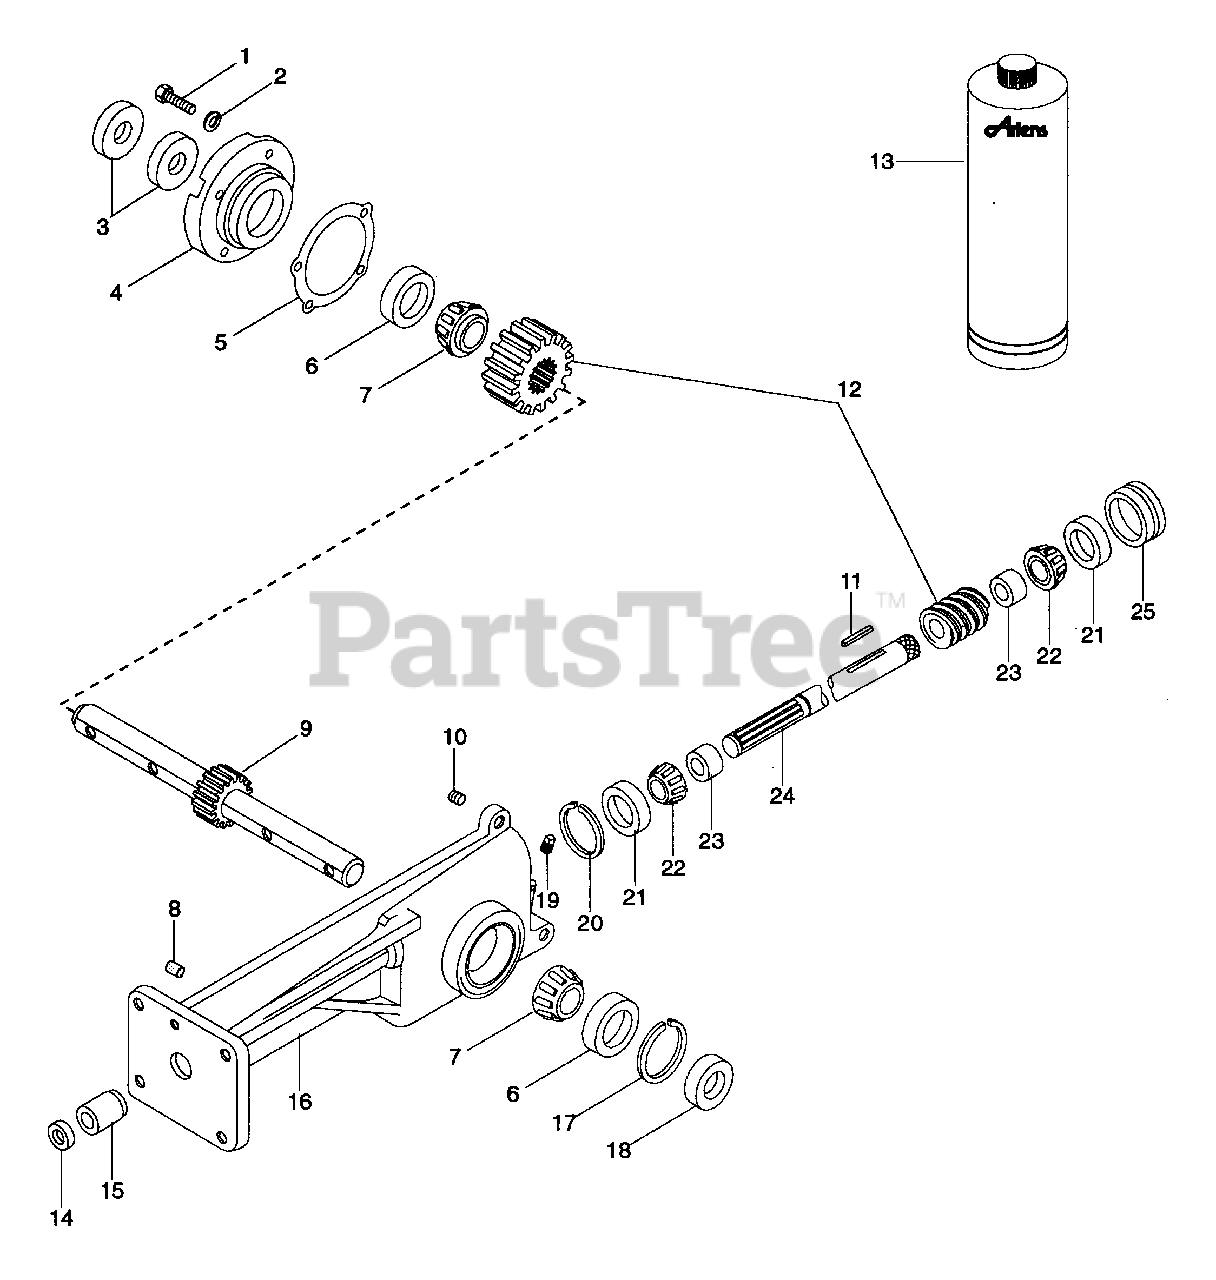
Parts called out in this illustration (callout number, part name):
1	BLT-HEX .38-16X1.00 PL GR5
2	WSHR-LK .375X.115 HVY PL
3	SEAL 1.000X1.785X.250
3	SEAL 1.250X2.00X.250
4	BEARING FLANGE
5	SERVICE KIT
6	BRG-CUP1.980X.420
6	BRG-CUP 2.328X.465
7	BRG-CONE 1.0X.58
7	BRG-CONE 1.25X.66
8	BREATHER
9	TINE SHAFT
10	SCR-SET .25-20X.25 SKHCUPNY OH
11	KEY-SQ .188X1.0X.188 SAE 8630
12	WORM & WORM GEAR SERVICE ASSY
12	WORM AND WORM GEAR ASSEMBLY
13	ARIENS 16 OZ.BOTTLE OF L2 LUBE
14	SEAL .750X1.000X.125
15	BRG-NEEDLE .750X1.0X.62
16	TILLER GEARCASE - C.I.
17	RG-RTNG-INT 1.969X.062
18	SEAL 1.000X1.980X.375
18	SEAL 1.250X2.00X.250
19	PIPE PLUG
20	RG-RTNG-INT 1.781X.062
21	BRG-CUP 1.781X.475
22	BRG-CONE .750X.61
23	BSHG, SPCR .755X1.12X.50 PM
24	WORM SHAFT
25	ADJUSTMENT PLUG
